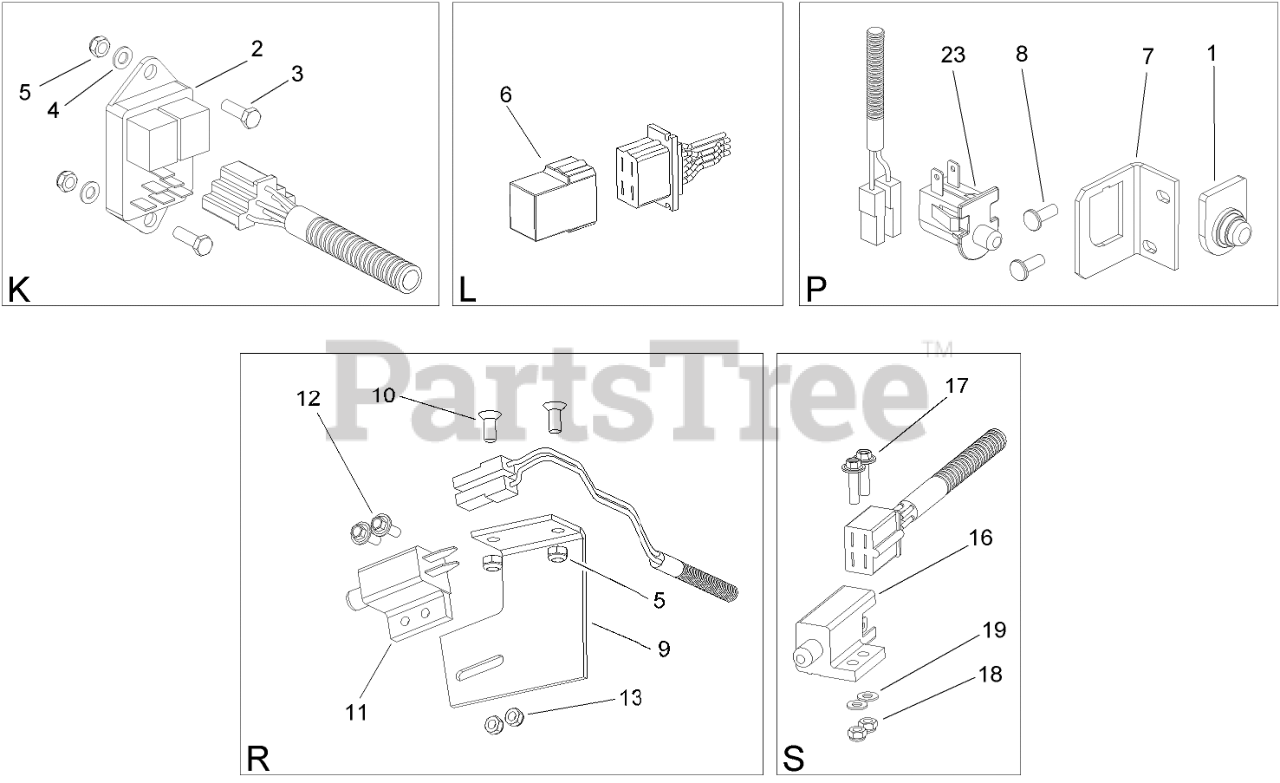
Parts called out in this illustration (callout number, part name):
1	COVER-PROTECTIVE
2	MODULE-CLUTCH
3	SCREW-HH
4	WASHER
5	NUT-LOCK
6	CIRCUIT-MEMORY
7	HOLDER-SWITCH
9	HOLDER-SWITCH
11	SWITCH-POLE, SINGLE
13	NUT-HEX
16	Switch-Delta
18	NUT-LOCK
19	WASHER
23	SWITCH-DELTA
